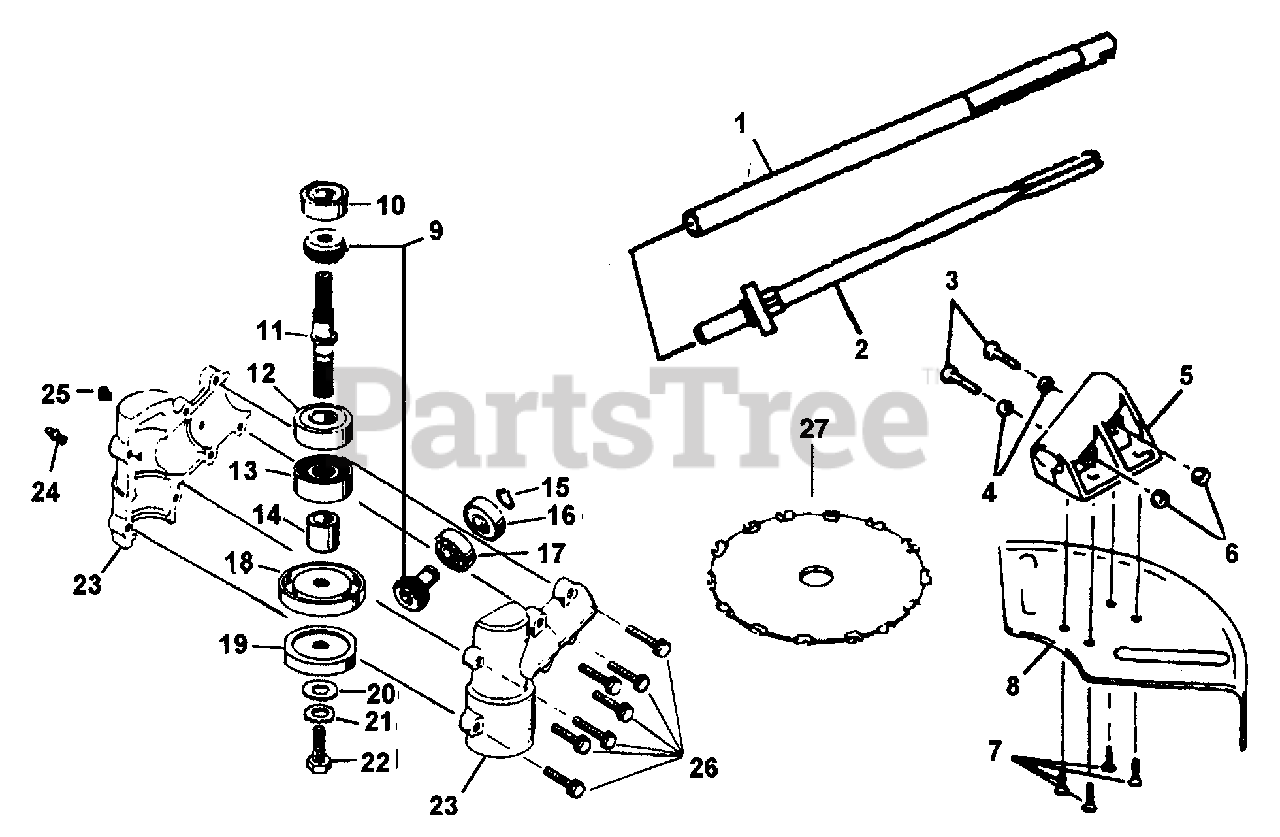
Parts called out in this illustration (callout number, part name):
1	TUBE ASSY.
2	FLEX CABLE
3	SCREW
7	SCREW, SELF TAPPING
8	GUARD
10	BEARING
11	SHAFT, GEAR
12	BEARING
15	SNAP RING
16	BEARING
17	BEARING
19	HOLDER B
20	WASHER, FLAT
21	WASHER, LOCKING
22	BOLT, L.H. THREAD
23	HOUSING SET
24	ZERK FITTING
25	SCREW, SELF TAPPING
26	SCREW, SELF TAPPING
27	8" XRT BLADE
